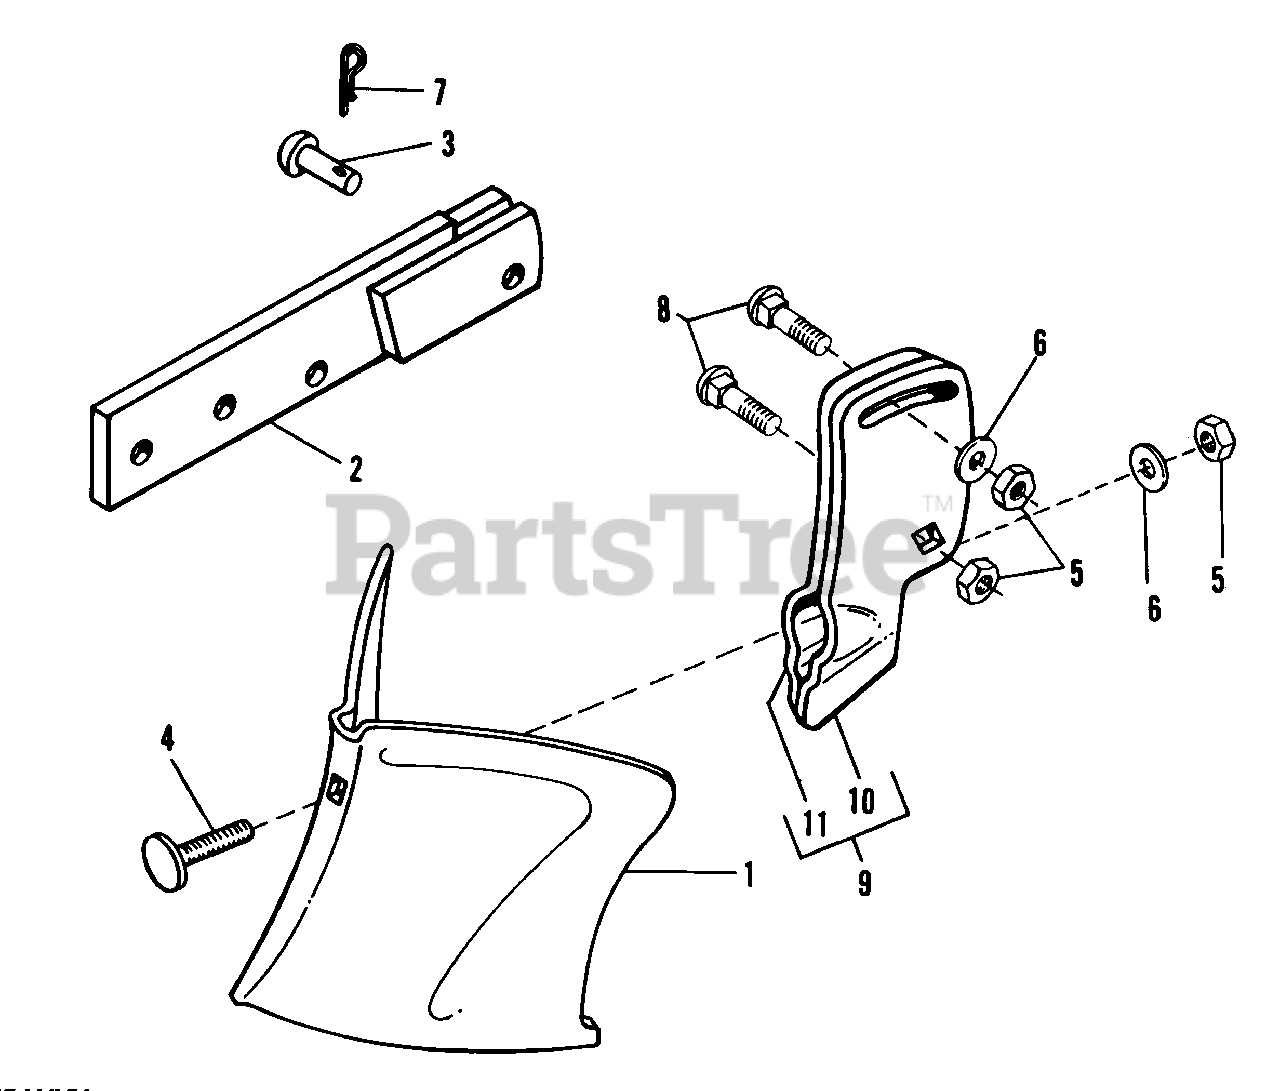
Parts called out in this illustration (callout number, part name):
1	FURROW OPENER, 8"
2	SUPPORT ASSY, Ext.
3	PIN
4	BOLT, Plow #3 Hd., 3/8-16 x 1-3/4, Gr. 2
5	NUT, Hex, 3/8-16
6	WASHER, Plain, 3/8
7	PIN, Quick, 1-7/8
8	BOLT, Rd. Hd., Sq. Nk., 3/8-16 x 1-1/4
9	HOLDER ASSY, Tool
10	HOLDER, R.H.
11	HOLDER, L.H.
